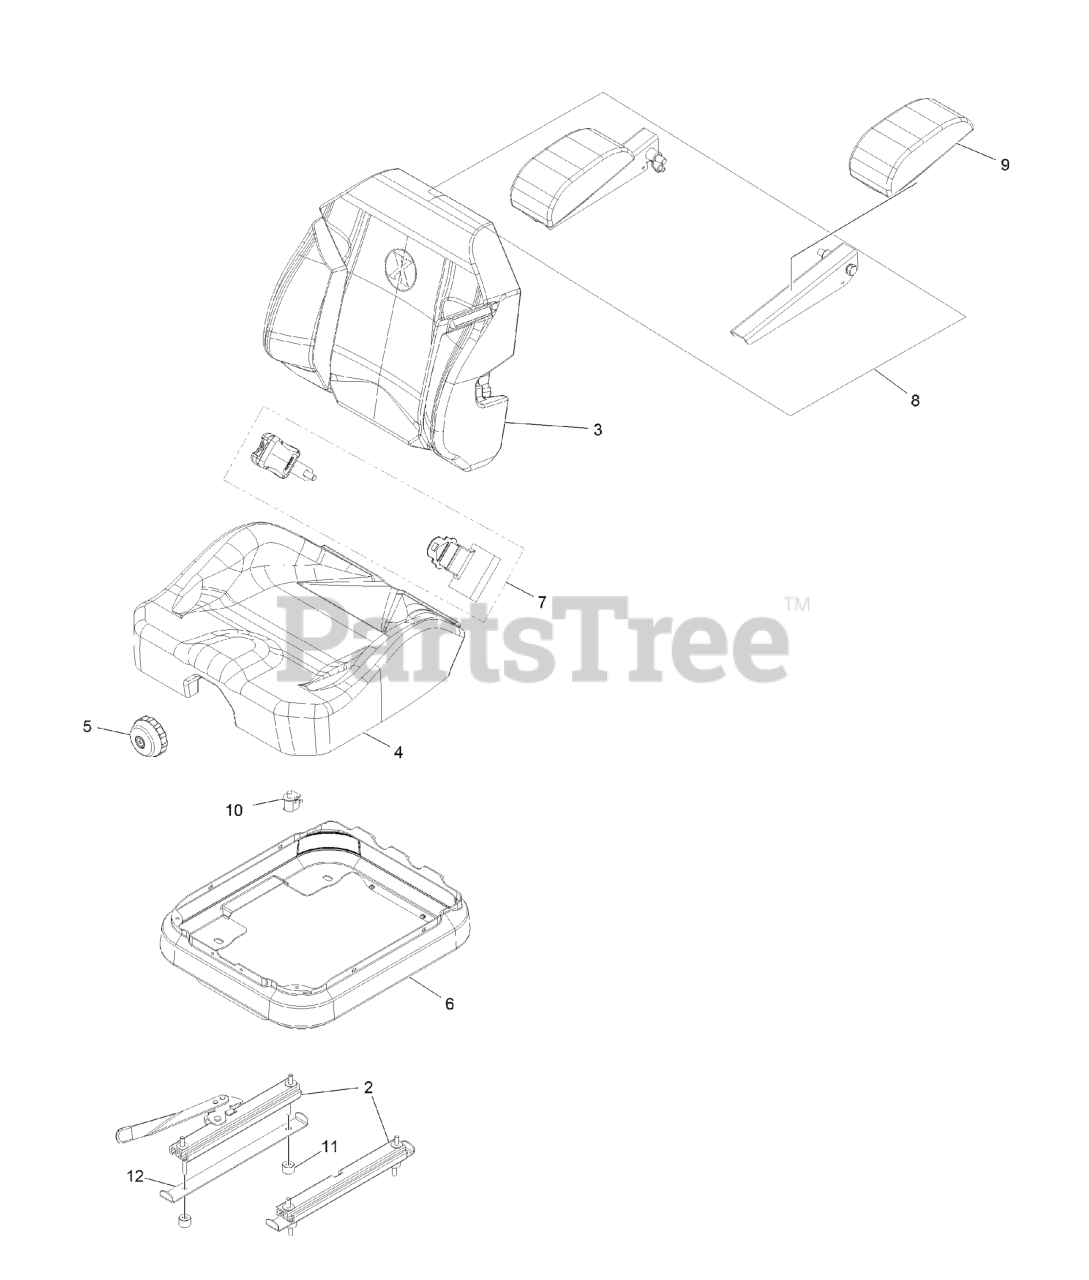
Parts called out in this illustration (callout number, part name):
2	SEAT TRACK SET
3	COVER-BACK 311463VN500
4	COVER-CUSHION 311464VN500
5	KNOB-ADJUSTER
6	COVER-SUSPENSION, BELLOWS
7	SEAT BELT SERVICE KIT
8	KIT-ARM REST SET
9	KIT-ARM REST PADS
10	SWITCH-BAIL
12	STOP, SEAT
